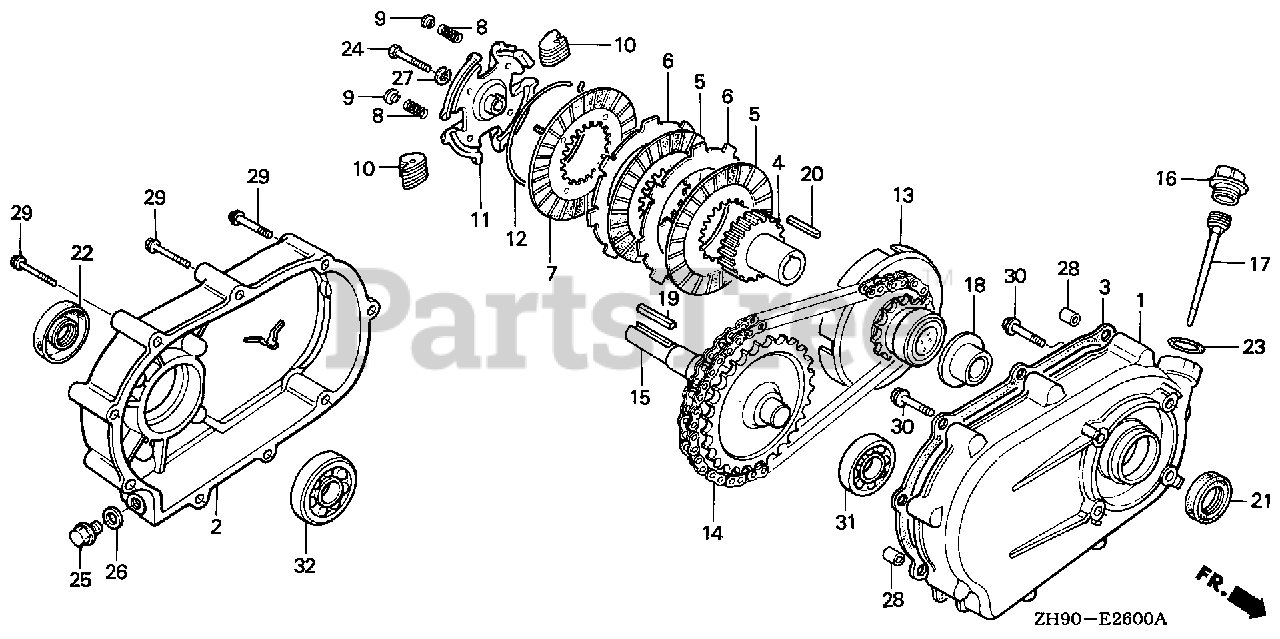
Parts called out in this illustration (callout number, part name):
1	CASE, REDUCTION
2	COVER, REDUCTION
3	GASKET, REDUCTION COVER
4	CENTER, CLUTCH (28T)
5	DISK, CLUTCH FRICTION
6	PLATE, CLUTCH
7	PLATE, CLUTCH PRESSURE
8	SPRING, CLUTCH FREE
9	HOLDER, CLUTCH SPRING
10	WEIGHT, CLUTCH
11	HOLDER, CLUTCH WEIGHT
12	CENTER, CLUTCH WEIGHT
13	SPROCKET, DRIVE (14T)
14	CHAIN, DRIVE (RK428SH-36LE)
15	SHAFT, P.T.O. (28T)
16	CAP, REDUCTION OIL (GRAY)
17	DIPSTICK, OIL
18	WASHER, THRUST (25MM)
19	KEY (7X7X33) (OVER SIZE) (YELLOW)
20	KEY, CLUTCH CENTER
21	OIL SEAL (30X46X8)
22	OIL SEAL (30X50X7)
23	O-RING (26X2.7)
24	BOLT, HEX. (8X35)
25	BOLT, DRAIN PLUG (12MM)
26	WASHER, DRAIN PLUG (12MM)
27	WASHER, SPRING (8MM)
28	PIN, DOWEL (8X14)
29	BOLT, FLANGE (6X50)
30	BOLT, FLANGE (8X32)
31	BEARING, RADIAL BALL (6205)
32	BEARING, RADIAL BALL (6206)
